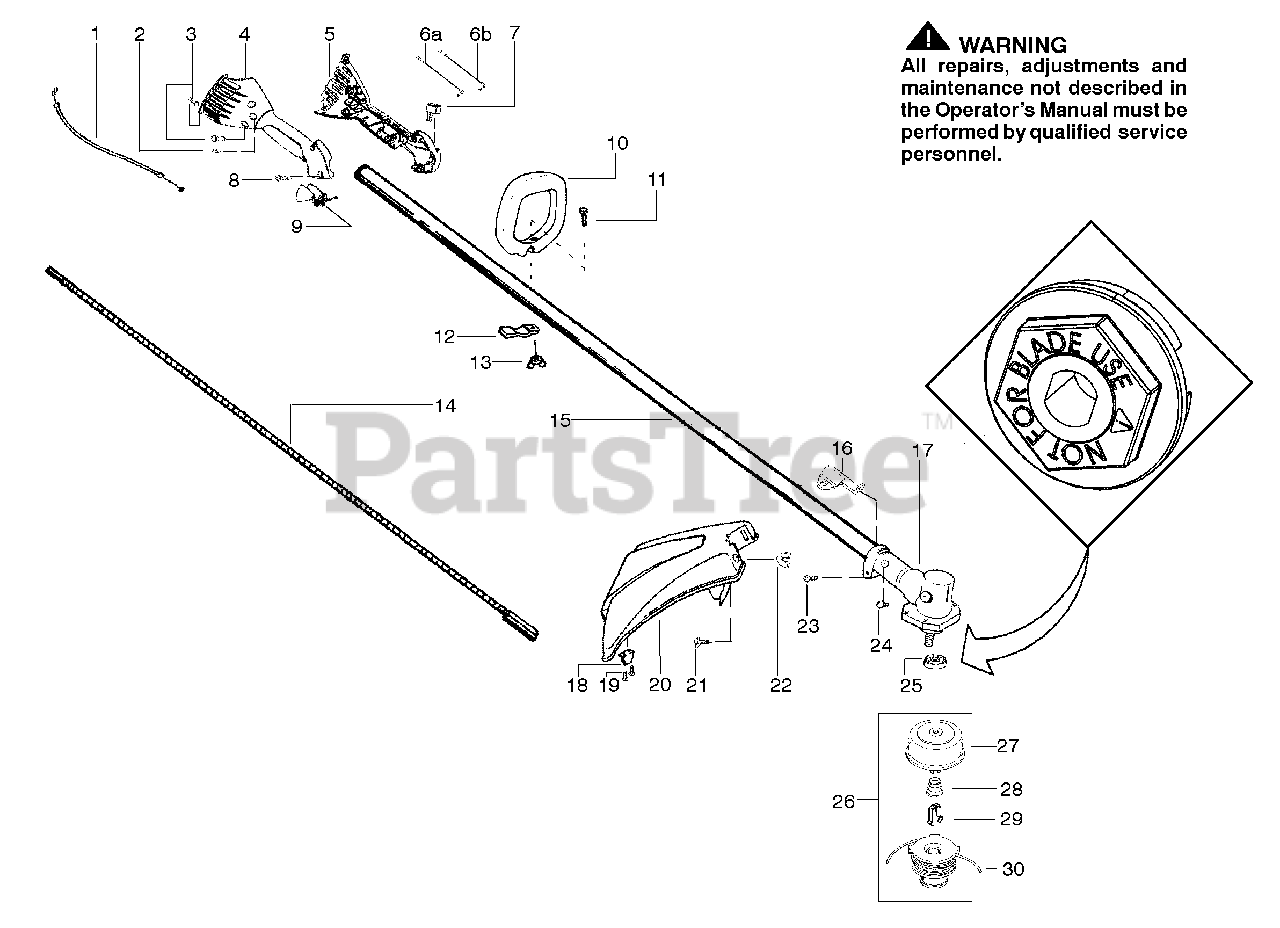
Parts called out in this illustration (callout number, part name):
1	Assy-Throttle cable
2	Screw
4	Hsg.-Throttle Right
5	Kit-Left Throttle Hsg.
6A	Assy-Wire lower
6B	Assy-Wire upper
7	Kit-Switch
9	Trigger-Throttle
10	Assy-Handle Assist
12	Clamp-Handle Assist
13	Wingnut
14	Shaft-Flex
15	Assy-Driveshaft
16	Bracket-Shield
17	Kit-Gearbox
18	Limiter-Line
19	Screw
20	Kit-Shield Ass'y.
22	Wingnut
25	Non-Blade Dust cup
26	Assy-Cutting Head
27	Assy. - Hub/Arbor (3/8lh , 2x)
28	Spring - Return
29	Retainer - Spool
30	Accy.-Wound Spool
